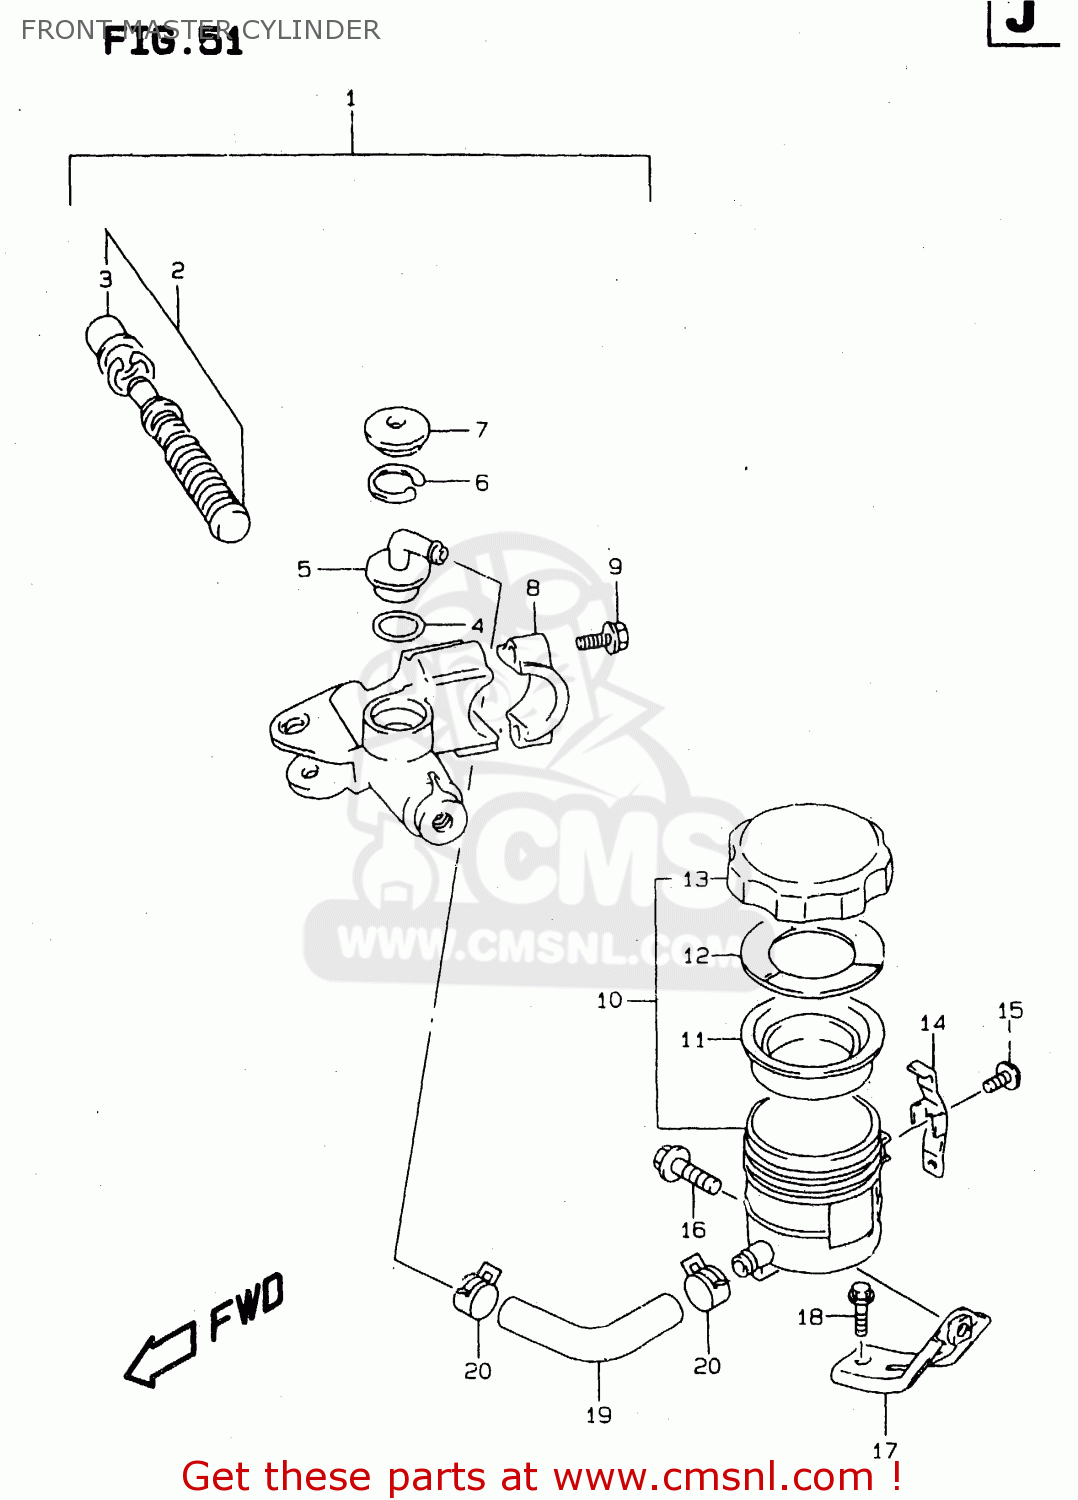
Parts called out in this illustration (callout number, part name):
1	CYLINDER ASSY,FR MASTER
2	PISTON & CUP SET
3	BOOT
4	O RING
5	CONNECTOR
6	CIRCLIP
7	COVER,DUST
8	HOLDER
9	BOLT(6X25)
10	TANK ASSY,RESERVOIR
11	DIAPHRAGM
12	PLATE,DIAPHRAGM
13	CAP
14	PLATE,RESERVOIR TANK CAP
15	SCREW
16	BOLT
17	BRACKET,RESERVOIR TANK FR
18	BOLT
19	HOSE,FR RESERVOIR TANK
20	CLAMP,RESERVOIR TANK FR
